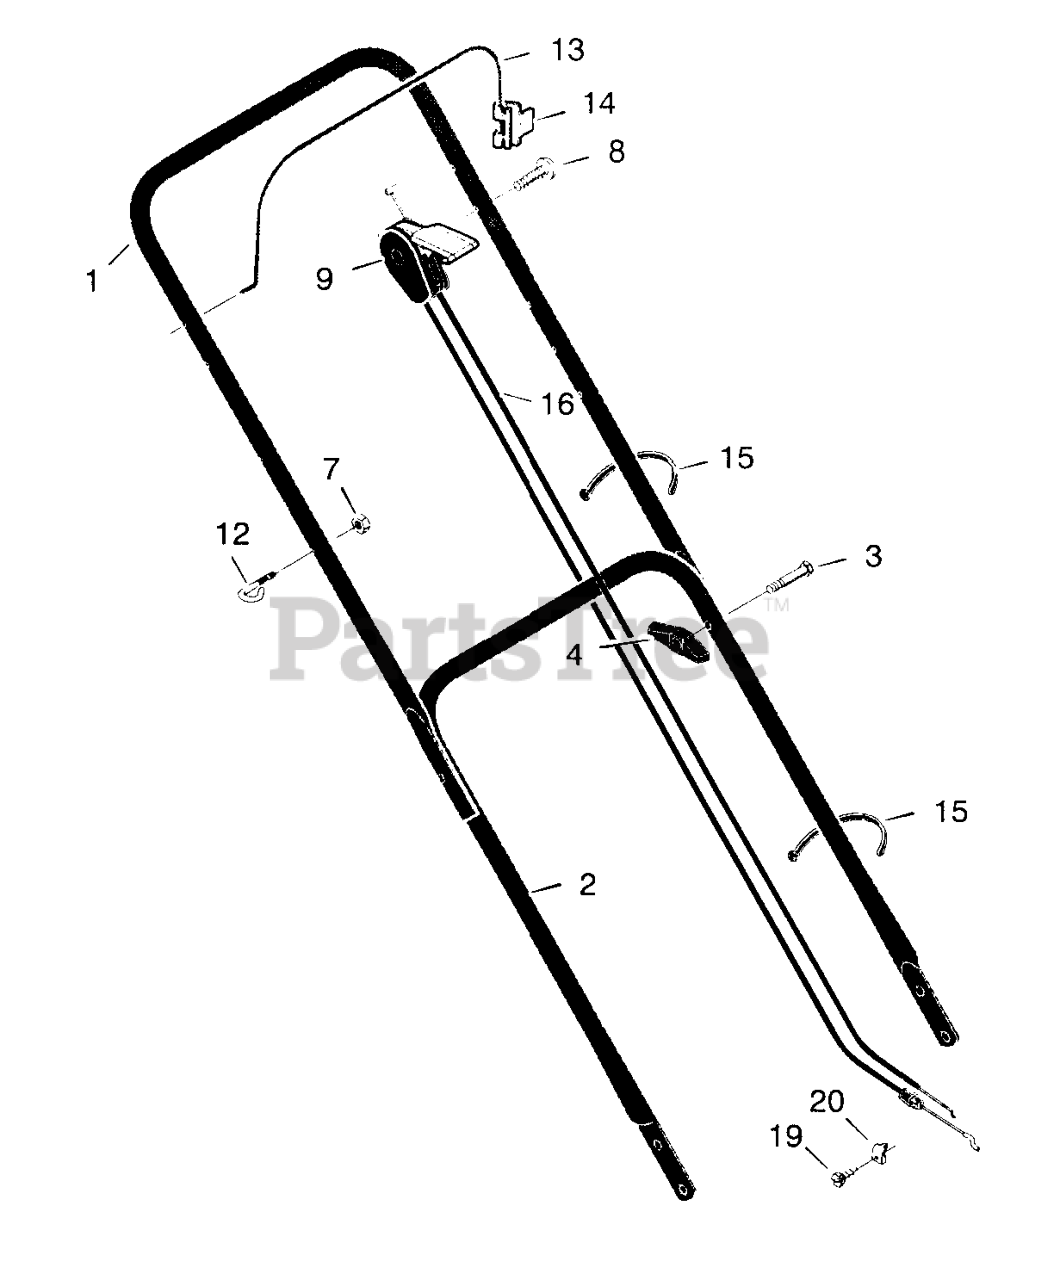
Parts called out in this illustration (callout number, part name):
1	Handle, Upper (Black)
2	Handle, Lower (Black)
4	Knob, Plastic
7	Locknut
9	Throttle Control
12	GUIDE, ROPE
13	Engine Stop Lever
14	Bracket, Stop Lever
15	Fastener, Cable
16	Engine Stop Cable
